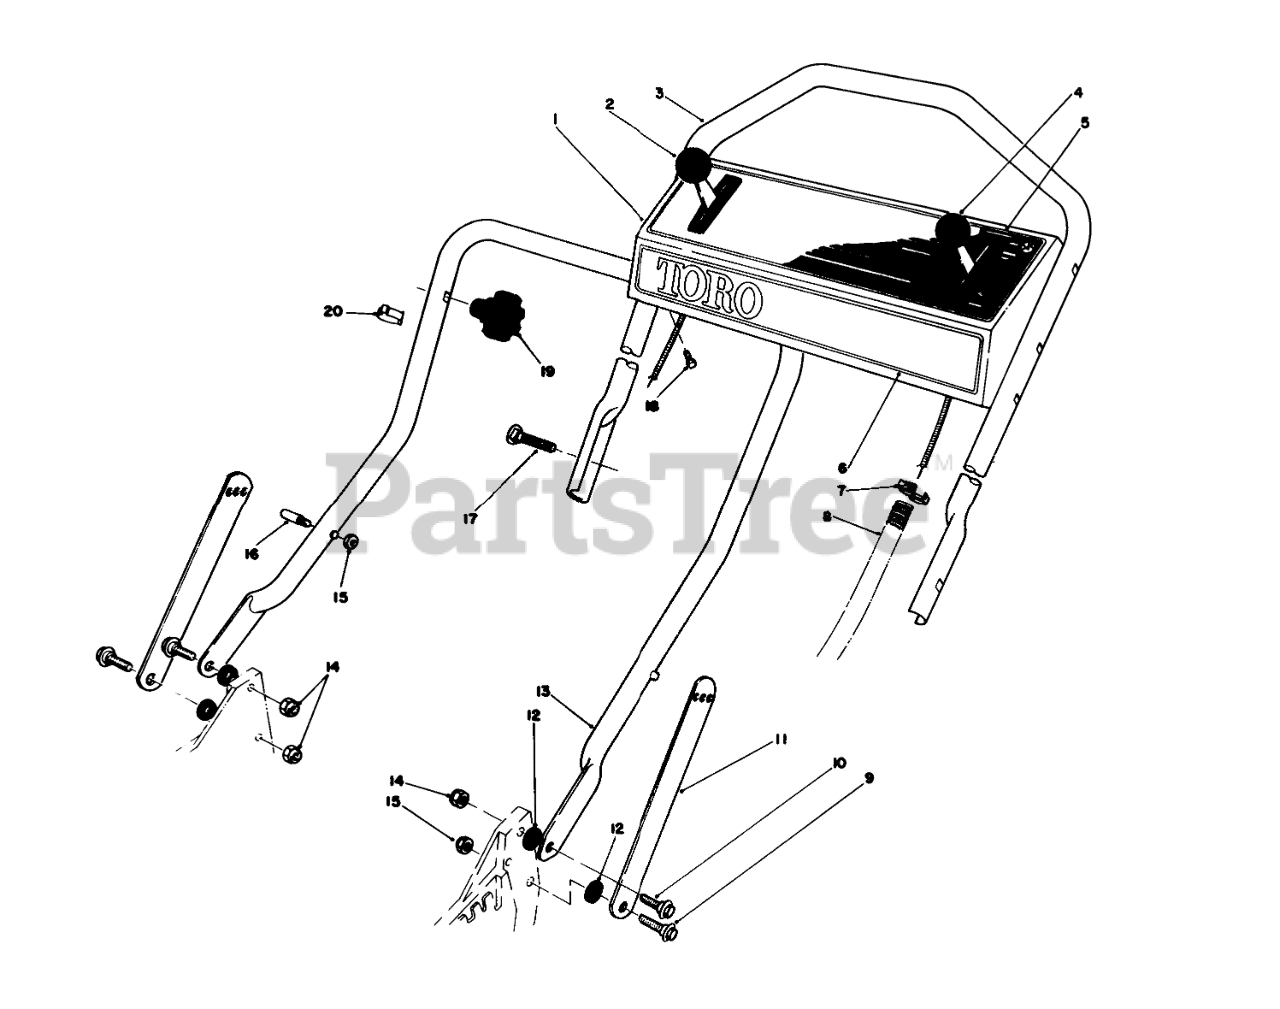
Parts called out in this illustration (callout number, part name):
1	Panel-Control (Incl. Ref. #5)
2	GROUND SPEED CONTROL
3	Handle-Upper
4	Control-Throttle (Bend #5)(Sheath 4. 55-7/8 inches)(Wire 4. 2-1/2 inches)
5	Decal-Instruction Panel
6	Decal-Toro
7	FITTING-RING
8	CONTROL CABLE COVER
9	SCREW-SHOULDER
10	SCREW-SHOULDER
11	Handle Latch
12	SPACER
13	LOWER HANDLE ASM
14	NUT-LOCK, NI
15	NUT-LOCK, NI
16	HANDLE PIN
17	5/16-18 X 2 HNDLE SCREW
18	SCREW-HWHTF
20	BOWDEN CLIP
